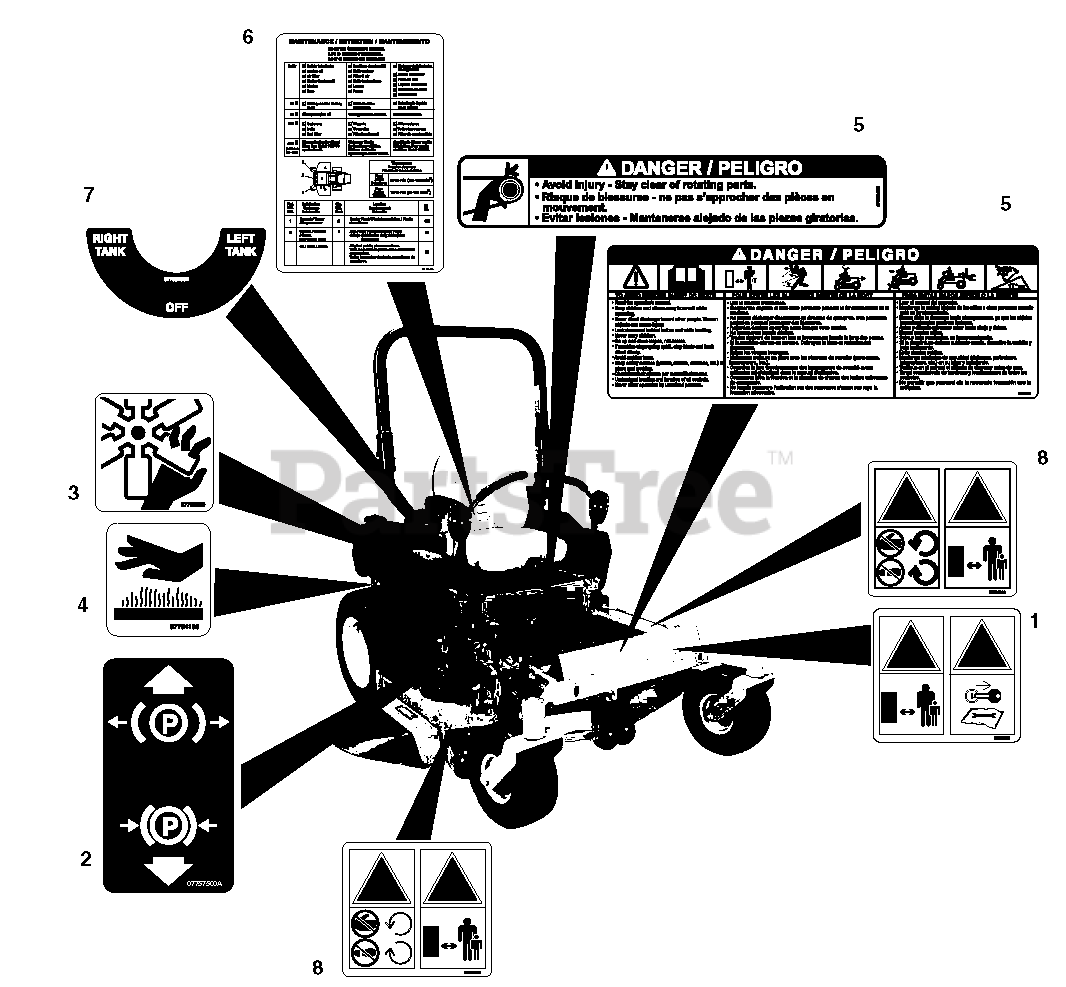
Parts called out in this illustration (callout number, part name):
1	Decal, CE Caution
2	Decal, Parking Brake Lever
3	Decal, Danger Fan
4	Decal, Hot Surface
5	Decal, Common Danger/Fuel
6	Decal, Maintenance Instructions
7	Decal, Fuel Control Valve
8	Decal, CE Deck
